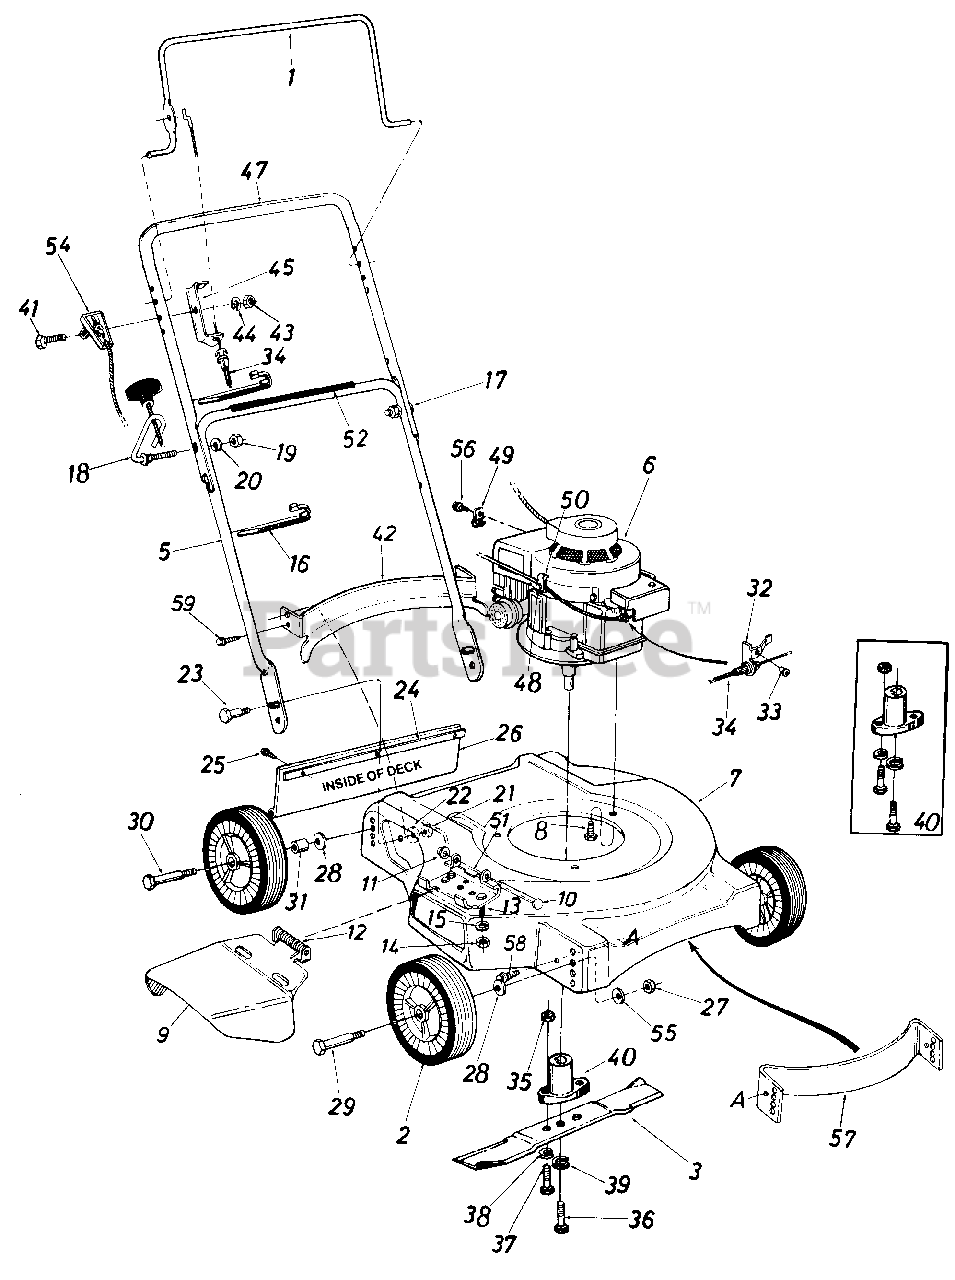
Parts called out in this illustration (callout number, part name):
1	Control Handle
2	Plastic Wheel Ass'y.
3	20" Blade
5	Lower Handle (Chrome)
6	Engine
9	Chute Deflector Ass y.
10	Pivot Pin
11	Cap Speed Nut 1/4" Rod
12	Torsion Spring
13	Hex Bolt 1/4-20 x .50" Lg.
14	Hex Nut 1/4-20 Thd.
15	L-Wash. 1/4" I.D.
16	Cable Tie
17	Curved Carriage Bolt 5/16-18 x 1.38" Lg.
18	Rope Guide Bolt
19	Hex Nut 5/16-18 Thd.
20	L-Wash. 5/16" I.D.
21	Hex Ins. L-Nut 5/16-18 Thd.
22	Bell-Wash. .345" I.D. x .88" O. D.
23	Shld. Bolt .437" Dia. x .180" Lg.
24	Retainer Strip
25	Hex Wash. Hd. Self-Tap Scr. 1/4" x .62" Lg.
26	Rear Flap Ass'y.
27	Hex Nut 3/8-16 Thd.
28	Bell-Wash. .400" I.D. x .88" O. D.
29	Shld. Bolt
30	Shld. Bolt
31	Spacer
32	Cable Bracket
33	Pop Rivet .156" Dia. x 379
34	Control Cable-43.0" Lg.
35	Hex Nut 5/16-24 Thd.
36	Hex Bolt 3/8-24 x 1.00" Lg. (Grade 5)
37	Hex Bolt 5/16-24 x 1.00" Lg. (Grade 5)
38	L-Wash. 5/16" I.D.
39	L-Wash. 3/8" I.D. Heavy Duty
40	Blade Adapter Kit
41	Hex Bolt 1/4-28 x 1.75" Lg.
42	Rear Baffle
43	Hex Nut 1/4-28 Thd.
44	L-Wash. 1/4" I.D.
45	Cable Mounting Brkt.
47	Upper Handle (Chrome)
48	Hex B-Tap Scr. #10 x .38" Lg.
49	Casing Clamp
50	Casing Clamp
51	Hinge Plate
52	Instruction Label-Handle
54	Throttle Control Ass'y. Comp. -B&S
55	Bell-Wash. .39" I.D. x 1.13" O.D.
56	Hex AB-Tap Scr. #8 x .38" Lg.
57	Baffle
58	Hex B-Tap Screw 1/4 x .38" Lg.
59	Hex Tap Screw #10 x .50" Lg.
